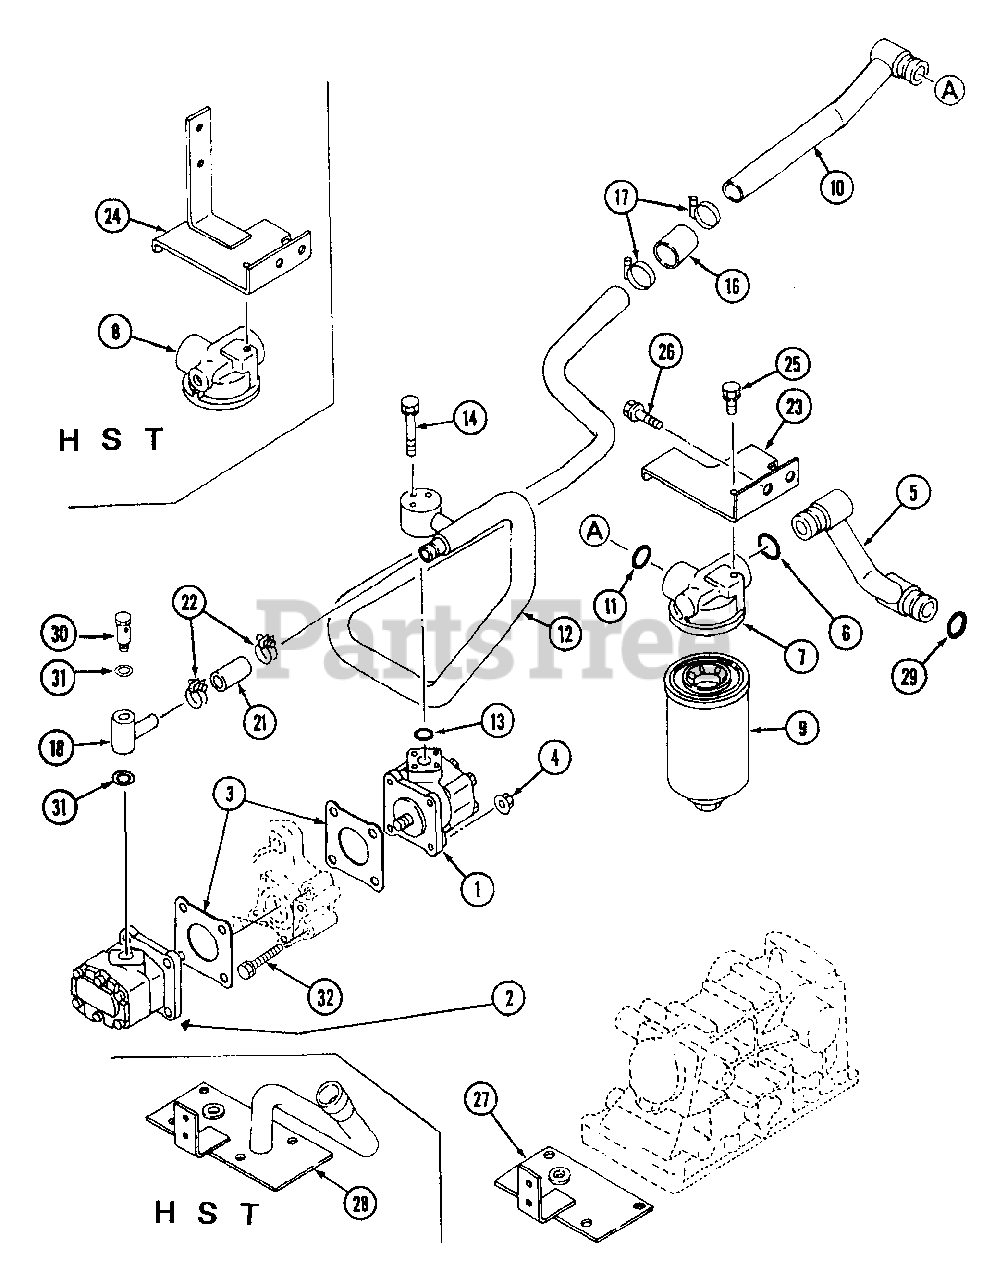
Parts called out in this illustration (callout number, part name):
1	Pump, Hydraulic
2	Pump, Hydraulic
5	Pipe, A Suction
7	Base, Filter (Gear)
8	Base, Filter (HST)
10	Pipe, B Suction
12	Pipe, C Suction
14	Bolt, W/Washer
23	Bracket (Gear)
24	Bracket (HST)
25	Bolt, W/Washer
26	Bolt, W/Washer
28	Cover (HST)
